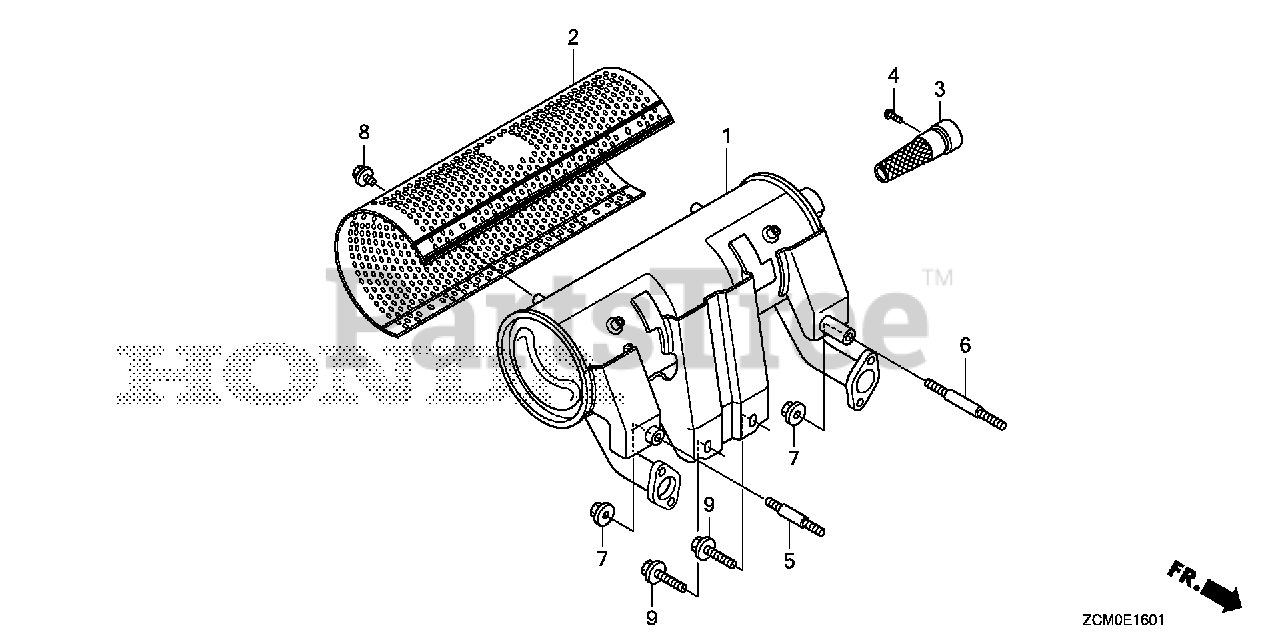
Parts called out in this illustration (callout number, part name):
1	MUFFLER (HIGH-L)
2	PROTECTOR, MUFFLER (HIGH) (FUTABA)
3	ARRESTER, SPARK
4	SCREW, TAPPING (5X8)
5	BOLT, STUD (8X45)
6	BOLT, STUD (8X60)
7	NUT, FLANGE (8MM)
8	BOLT, FLANGE (6X8)
9	BOLT, FLANGE (8X20)
